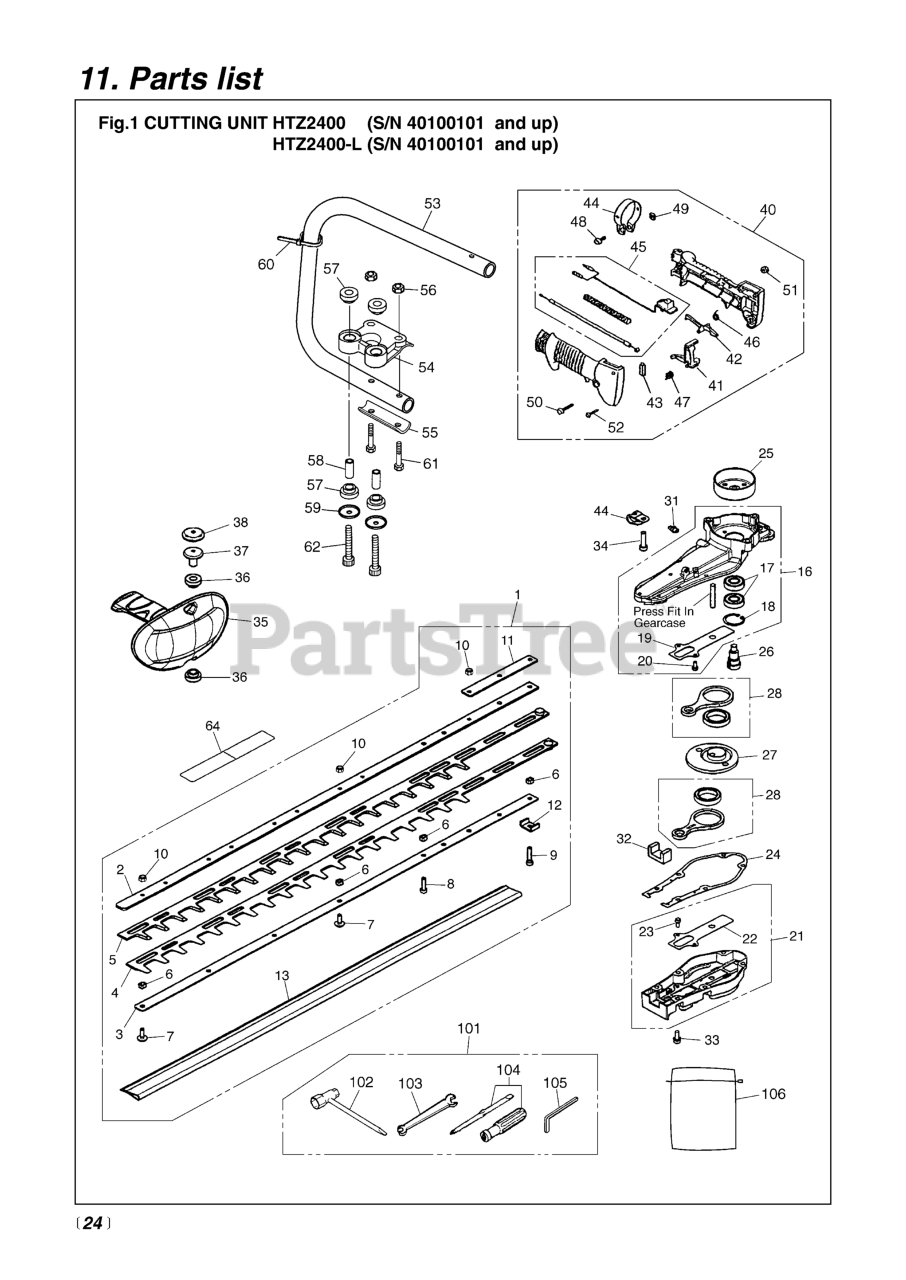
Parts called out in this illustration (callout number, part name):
1	BLADE ASSY
2	PLATE,UPPER
3	PLATE ,LOWER
4	BLADE LOWER
5	BLADE UPPER
6	SPACER
7	SCREW, BLADE
8	BOLT, M5 X 20
9	BOLT
10	NUT
11	PLATE
12	BRACKET
13	COVER,BLADE
16	GEARCASE COMP., UPPER
17	BEARING
18	RING, SNAP, M28 x 1.2
20	BOLT
21	CASE-BOTTOM-A
23	BOLT
24	GASKET
26	GEAR, DRIVE
27	GEAR, DRIVEN
28	ROD-A
31	FITTING, GREASE
32	FELT
33	BOLT
34	BOLT, M6 X 25
35	HANDLE-R-COMP
36	SPACER
37	HOLDER
38	CAP
40	LEVER-ASSY
41	LEVER
42	LEVER
43	TOP
44	BAND
45	CABLE-ASSY
46	SPRING
47	SPRING
49	NUT
50	SCREW
51	NUT
52	SCREW
53	PIPE
54	MOUNT
56	NUT, M5 X 4
57	ABSORBER
58	COLLAR
59	WASHER
61	BOLT, M5 X 30
62	BOLT, M6 x 1.35
64	LABEL CAUTION
101	TOOL-SET
103	SPANNER, 8 X 10 (RPLS 2540- )
104	SCREWDRIVER
105	WRENCH (TOOL)
